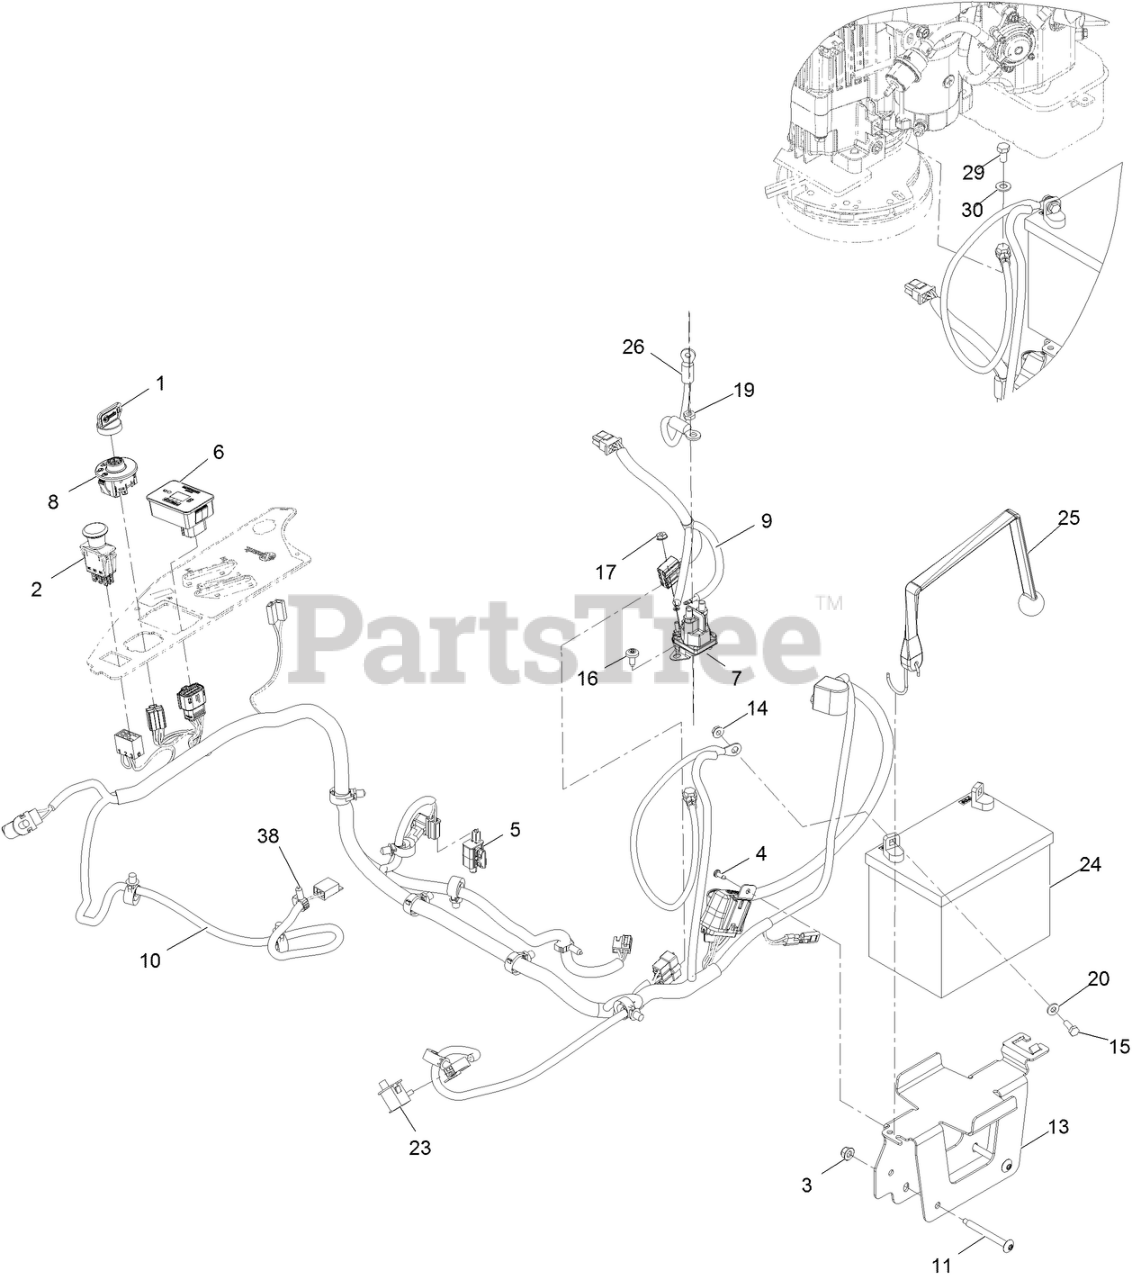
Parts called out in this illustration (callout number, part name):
1	KEYS-IGNITION (SPARE PAIR
1	KEY-IGNITION
2	SWITCH-PTO
3	NUT-HF, NI
4	SCREW-FORMING, THREAD
6	MODULE ASM
7	SOLENOID
8	SWITCH-IGNITION
9	ADAPTER-HARNESS, WIRE
10	HARNESS-WIRE
11	SCREW-TORX
13	TRAY-BATTERY
15	SCREW-HH
16	SCREW-TORX
17	NUT-KEPS
19	NUT-JAM
20	WASHER-FLAT
23	SWITCH-BAIL
24	Battery
25	STRAP-BUNGEE
26	CABLE-BATTERY, POSITIVE
29	SCREW-HH
30	WASHER-PLAIN
38	CLIP-HARNESS
